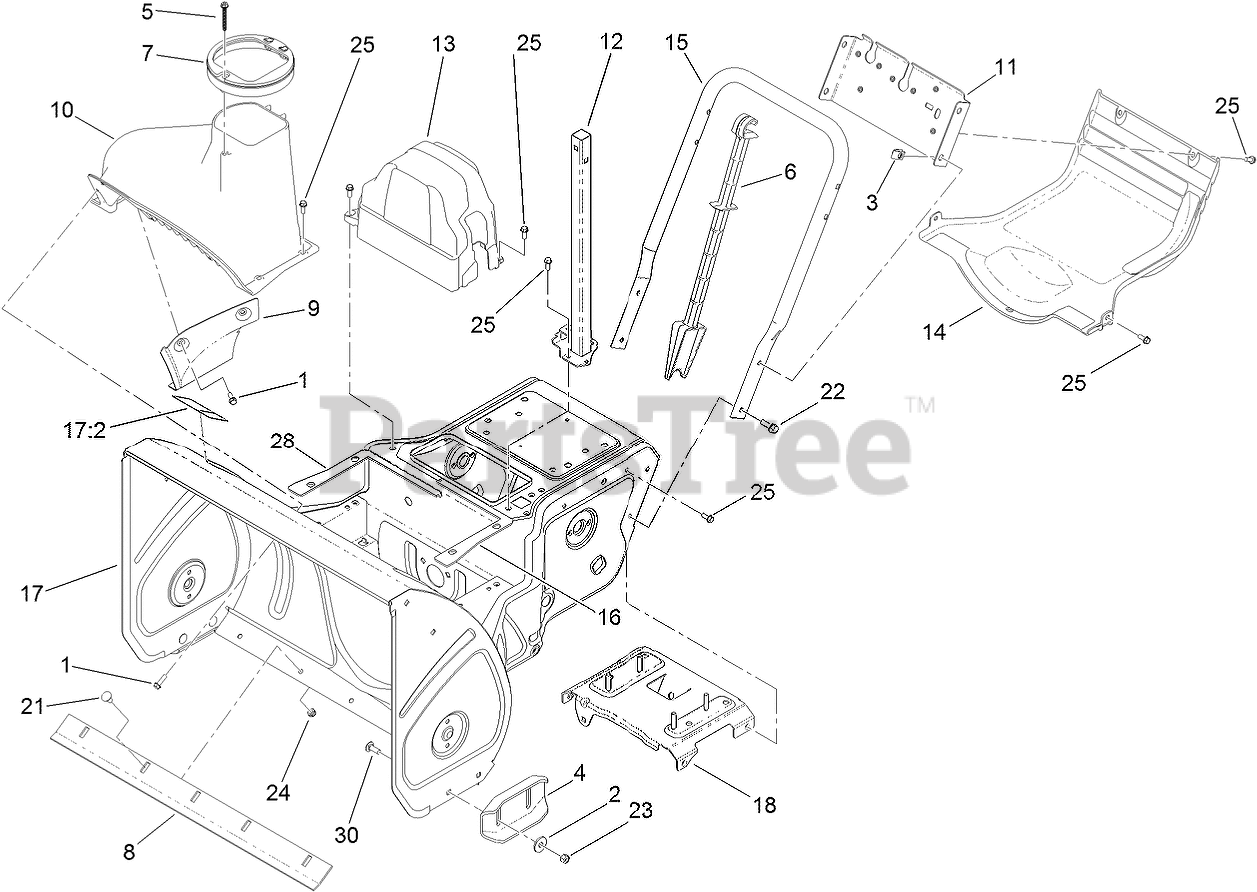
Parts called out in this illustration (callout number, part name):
1	SCREW-HWH
2	WASHER
3	NUT-U
5	SCREW-HWH, PLASTITE
6	STICK-CLEANOUT
7	GUIDE-CHUTE
8	SCRAPER-24 INCH
9	COVER-LINER
11	BRACE-FRAME
12	SUPPORT-CHUTE
13	COVER-BELT
14	COVER-LOWER
15	HANDLE-LOWER
16	SEAL-HOUSING, LH
17	FRAME ASM
17:2	DECAL-DANGER, AUGER
18	PLATE-STUD ENGINE
21	SCREW-CARR
22	SCREW-HHF
23	NUT-LOCK, NI
24	NUT-LOCK, NI
25	SCREW-HWH
28	SEAL-HOUSING, RH
30	SCREW-CARR
